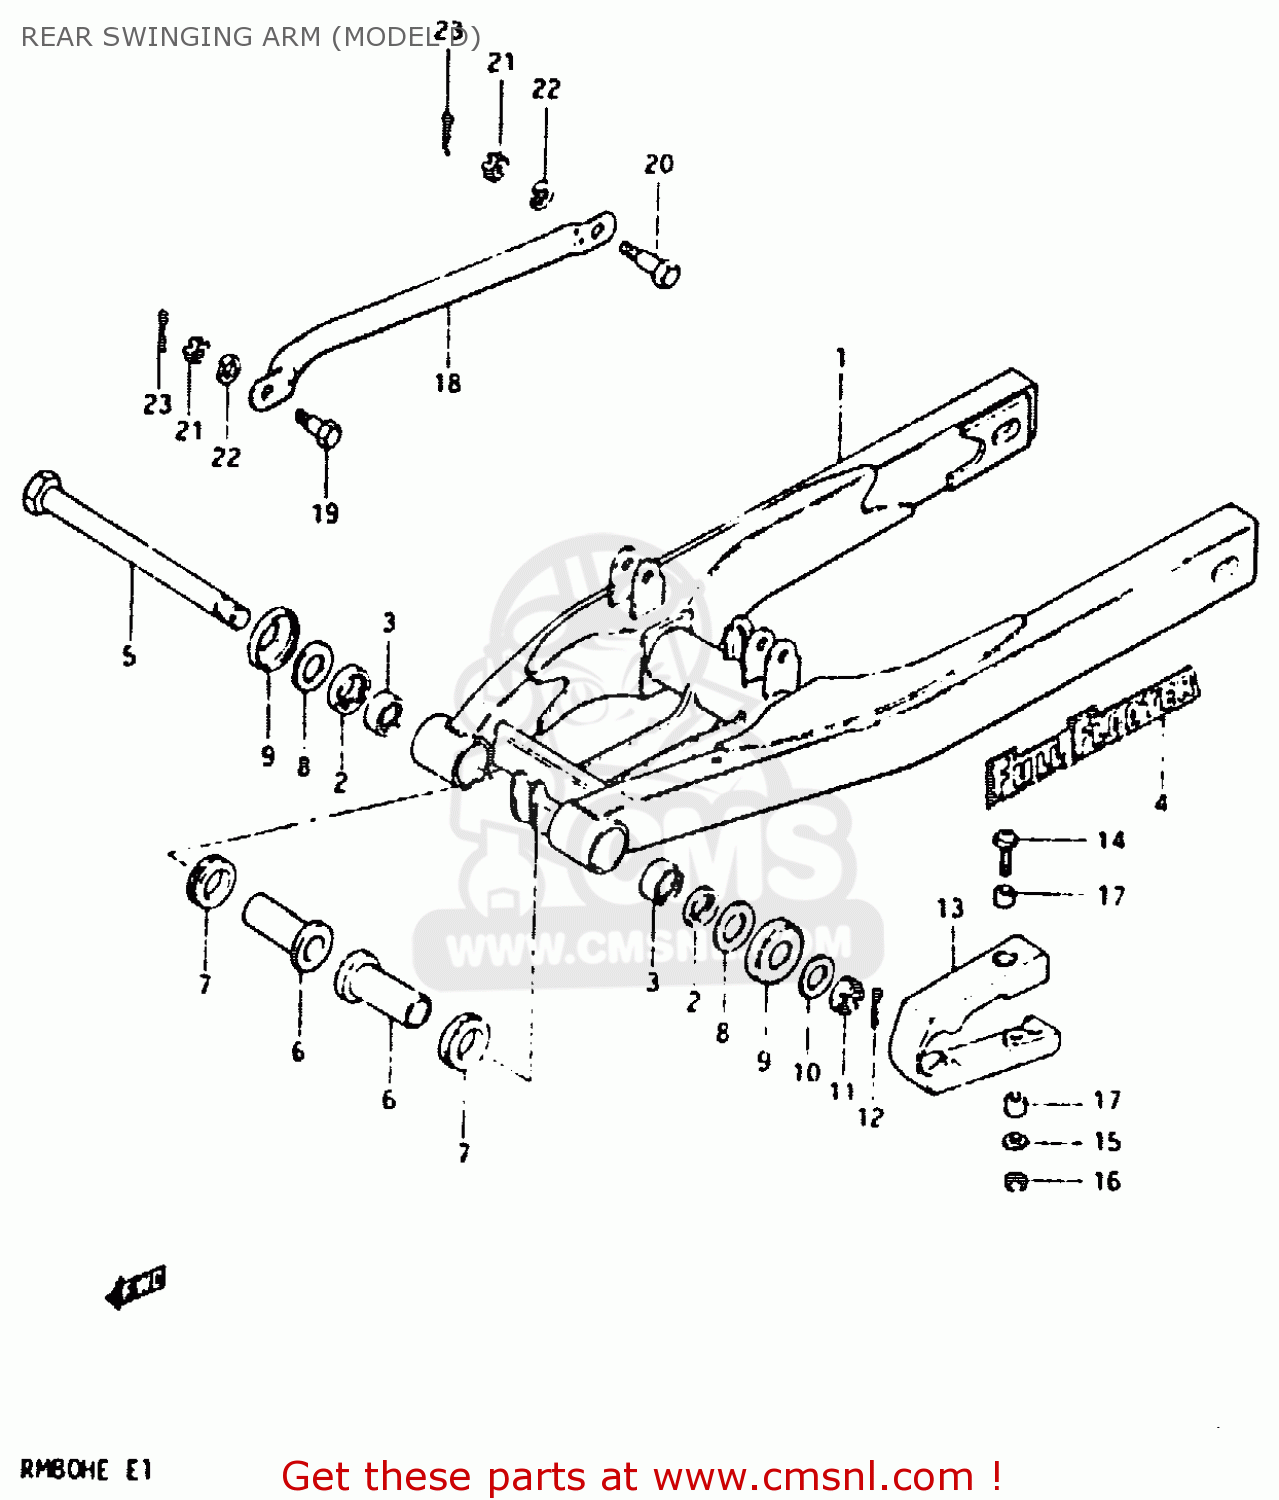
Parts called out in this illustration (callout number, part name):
1	REAR SWINGING ARM SET
2	SEAL,OIL(17X24X3)
3	ROLLER BEARING (17X24X25)
4	EMBLEM,SWING ARM
5	SHAFT,REAR SWING ARM
6	SPACER,RR SWGARM PIVOT
7	SEAL,OIL(17X24X5)
8	WASHER
9	COVER,RR SWGARM DUST SEAL
10	WASHER
11	NUT, REAR AXLE
12	COTTER PIN
13	BUFFER,CHAIN TOUCH DEFLECTOR
14	SCREW,CHAIN TOUCH DEFEND
15	WASHER
16	NUT
17	SPACER (5.5X8X4)
18	TORQUC LINK, REAR (GOLD)
19	BOLT(8X22)
20	BOLT(8X21)
21	NUT
22	LOCK WASHER
23	PIN 20X20
